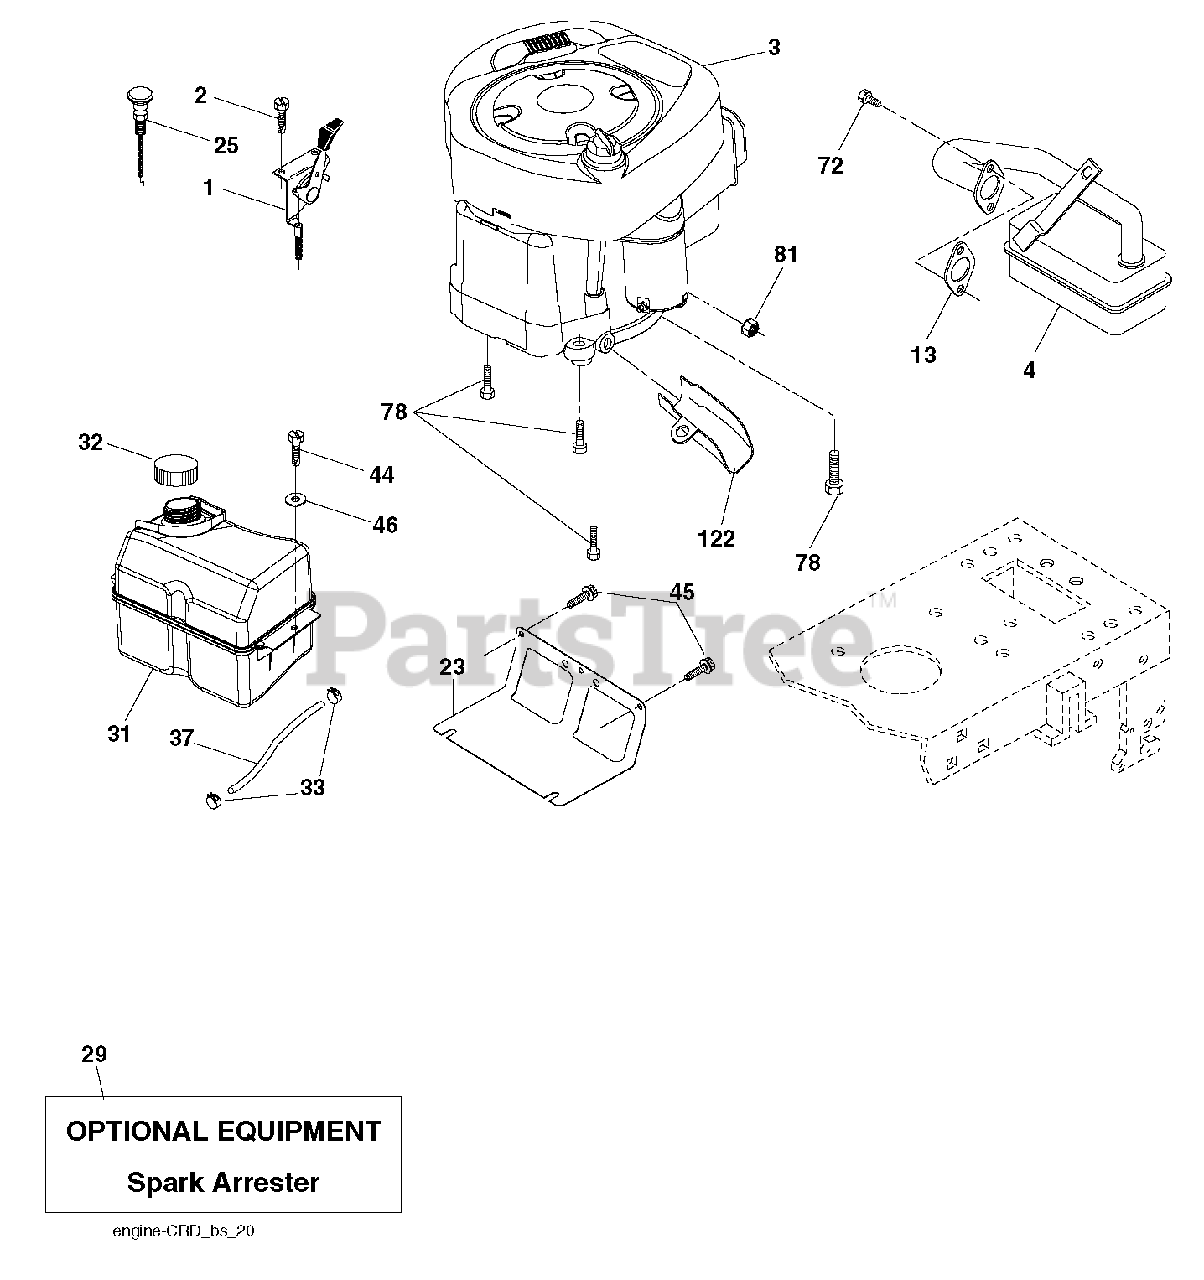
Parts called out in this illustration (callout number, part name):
1	CONTROL.THROTTLE/CHOKE.BLACK
2	SCREW
4	MUFFLER.LT.BRIGGS.14HP.IC/OHV
13	REPL BY 532 27 22-93
23	SHIELD.BROWNING.DBR.GUARD
25	KNOB.ERGO.EXTENDED.RED (1 2)
29	KIT.SPARK ARRESTOR 794945 B&S
31	TANK.FUEL.FRT.N/CAP.2.0GAL.DAP
32	CAP ASM.FUEL.2.25"FR.
33	HOSE CLAMP
37	LINE.FUEL.20
44	SCREW HEXWSHR 1/4-20X3/4
45	SCREW, 3/8-16X3/4
72	SCREW.SOCKET HD.5/16-1
78	SCREW.3/8-16
81	NUT
122	EXTENSION DRAIN OIL
